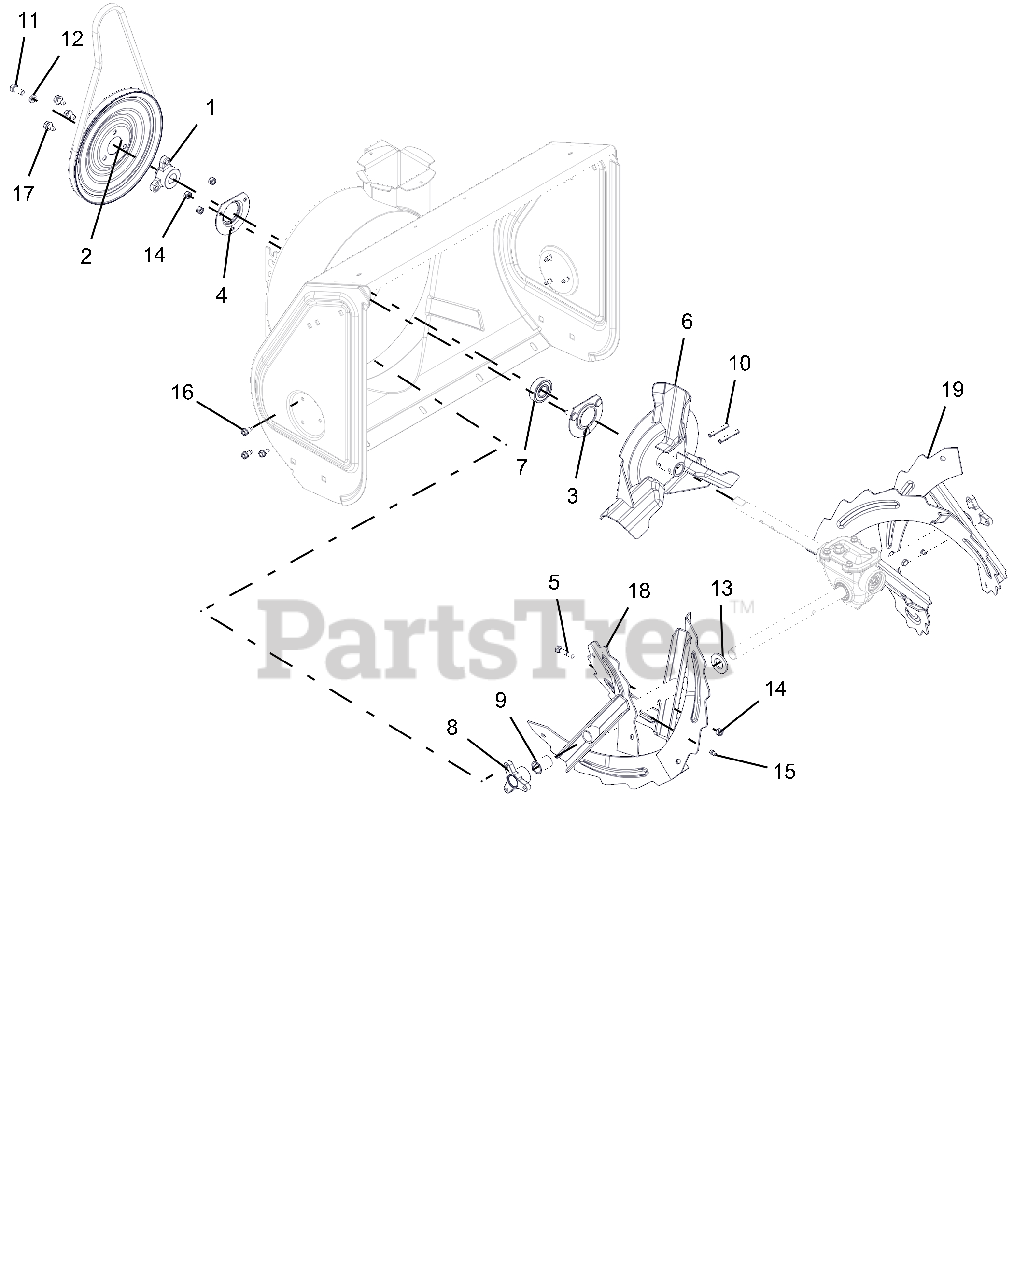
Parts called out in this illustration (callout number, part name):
1	PULLEY HUB, BOLT-ON D-BORE .75
2	PULLEY,SPIN FORM SINGLE GROOVE
3	BEARING FLANGE
4	BEARING FLANGE
5	SHEAR BOLT
6	IMPELLER, COMPACT 12" 3-BLADE
7	BRG-BALL .750X1.750X.50
8	BUSHING, RAKE SHAFT .75"
9	BSHG-FLG SPLIT NYLINER .75"ID
10	PIN-ROLL .250X1.75
11	BLT-HEX .31-24X.75 YWZC GR5
12	WSHR-LK .312X.097 HVY YWZC
13	@WSHR-FL-STL.812X1.50X.135YWZC
14	@NUT-LK-CTR .25-20 YWZC
15	ZERK,FITTING .25X.125 DRIVE IN
16	SCR-TAP .25-20X.50 HWH TR YWZ
17	@SCR-TAP .31-18X.50 HWH TR YWZ
18	RAKE, 24" RH, BLK SERR W/ZERK
19	RAKE, 24" LH, BLK SERR W/ZERK
